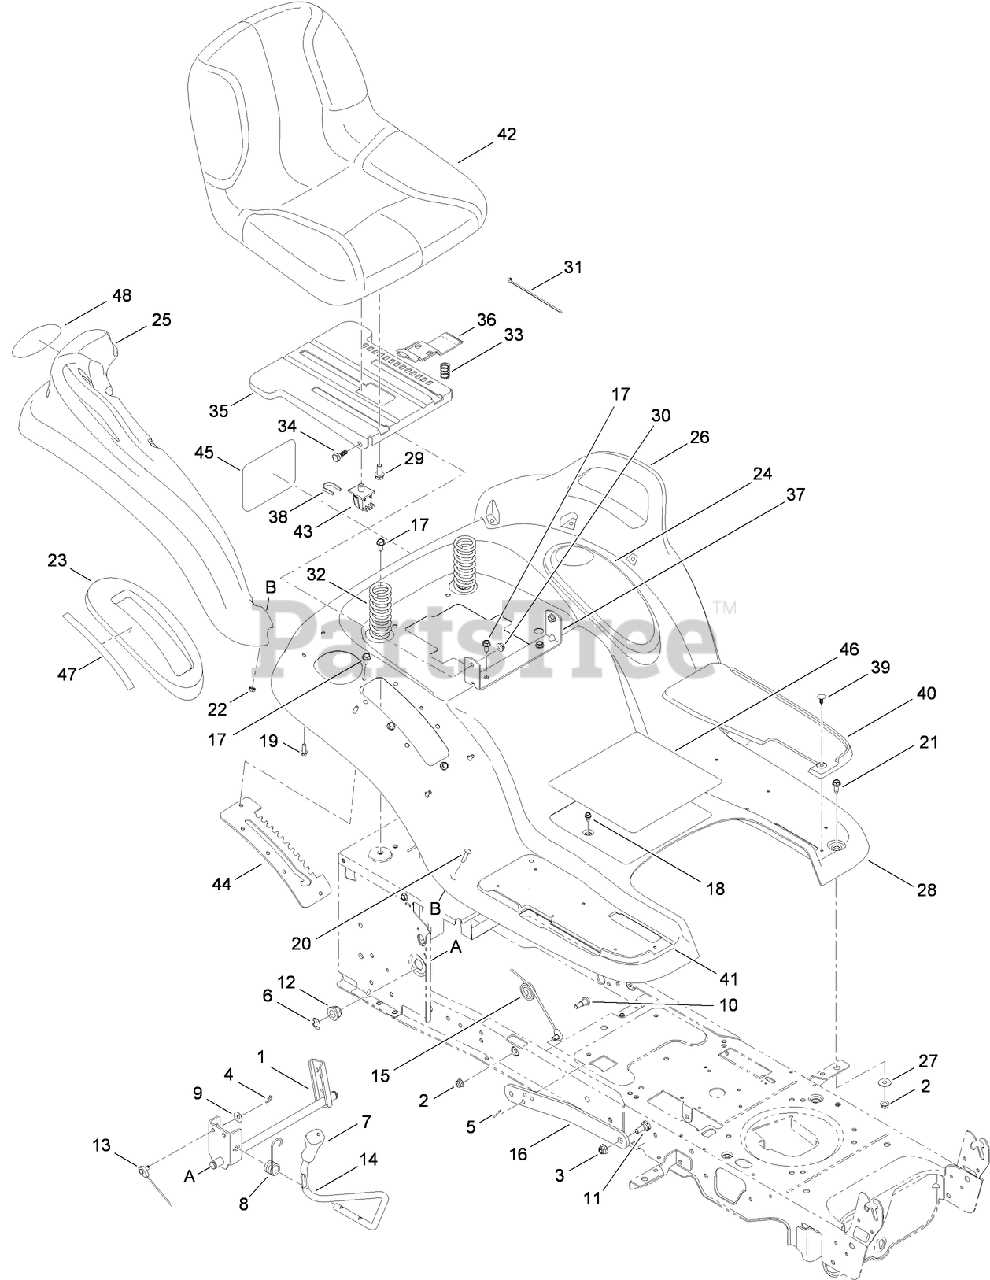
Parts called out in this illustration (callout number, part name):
1	LIFT SHAFT ASM
2	NUT-LOCK, FLANGE
3	NUT-LOCK, FLANGE
4	PIN-COTTER
5	PIN-COTTER
6	RING-E
7	GRIP-HANDLE
8	SPRING-TORSION
9	WASHER-SPRING
10	BOLT-SHOULDER
11	BOLT-SHOULDER
12	BEARING-FLANGE
13	CABLE-LIFT
14	HANDLE-LIFT
15	PULLEY-CABLE
16	ARM-LIFT
17	SCREW-TAP
18	SCREW-HWHTF
19	SCREW-TAP
20	SCREW-CARR
21	SCREW-HWH
22	NUT-SEMS
23	COVER-LIFT, LEVER
24	COVER (W/CUP HOLDER)
25	FLARE-FENDER, RH
26	FLARE-FENDER, LH
27	WASHER-FLAT
28	FENDER
29	SCREW-HH
30	NUT-LOCK, FLANGE
31	TIE-CABLE
32	SPRING-COMPRESSION
33	SPRING-COMPRESSION
34	BOLT-SHOULDER
35	BRACKET-MOUNT, SEAT
36	LEVER-ADJUSTMENT, SEAT
37	BRACKET-PIVOT, SEAT
38	CLIP-RETENSION
39	CLIP-RATCHET, FASTENER
40	PAD-FOOT, LH
41	PAD-FOOT, RH
42	SEAT-HIGH
43	SWITCH-SEAT
44	BRACKET-LIFT
45	DECAL-TORO
46	DECAL-SAFETY
47	DECAL-HOC
48	REFLECTOR
